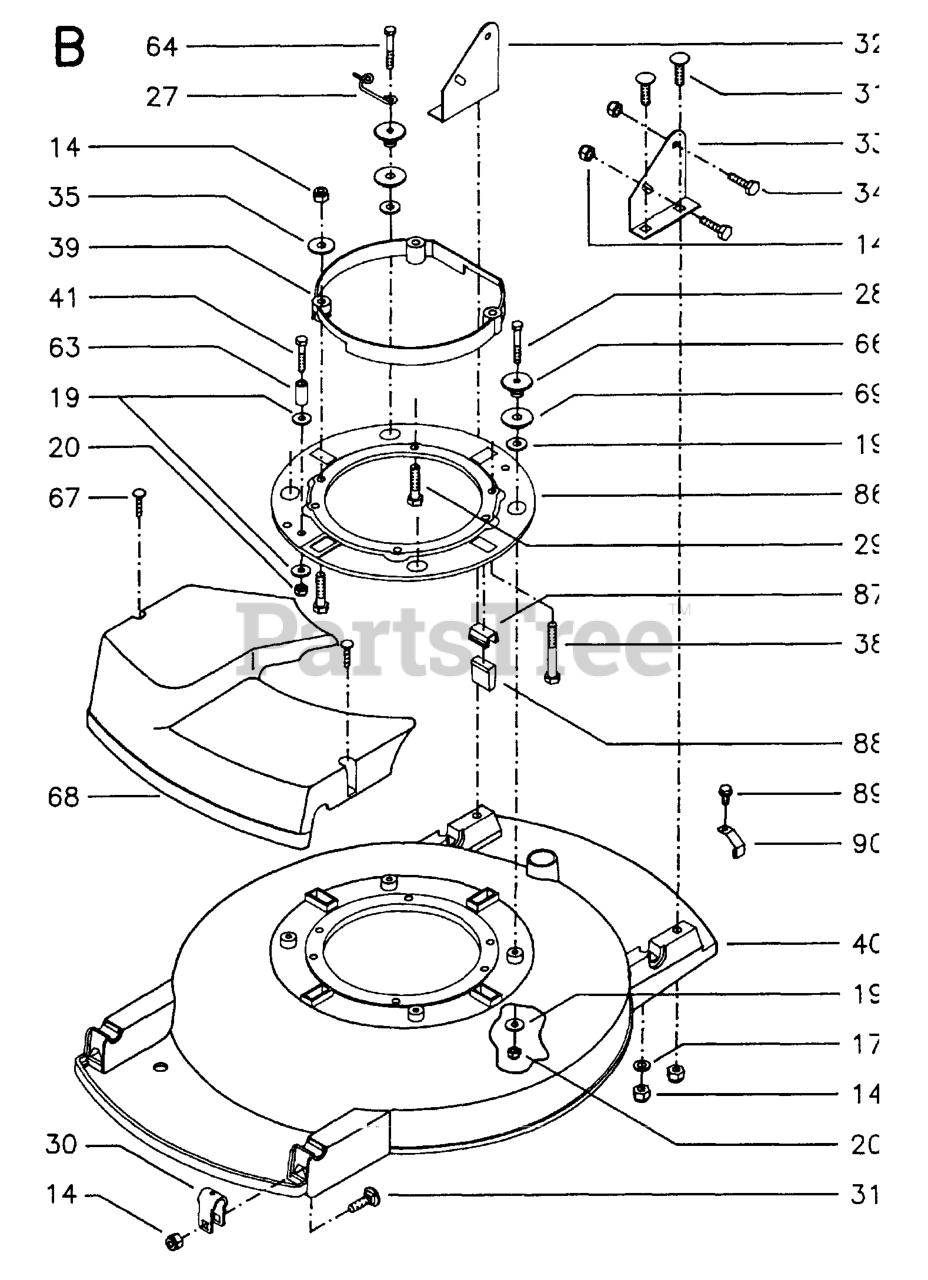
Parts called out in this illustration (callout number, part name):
14	LOCKNUT M8
17	WASHER - 15X7.3X1.6
20	LOCKNUT M6
30	BEARING HOLDER
32	HANDLE BRACKET
33	HANDLE BRACKET
34	BOLT - M8X16
41	BOLT FLANGE
69	RUBBER PIECE
88	DAMPER
